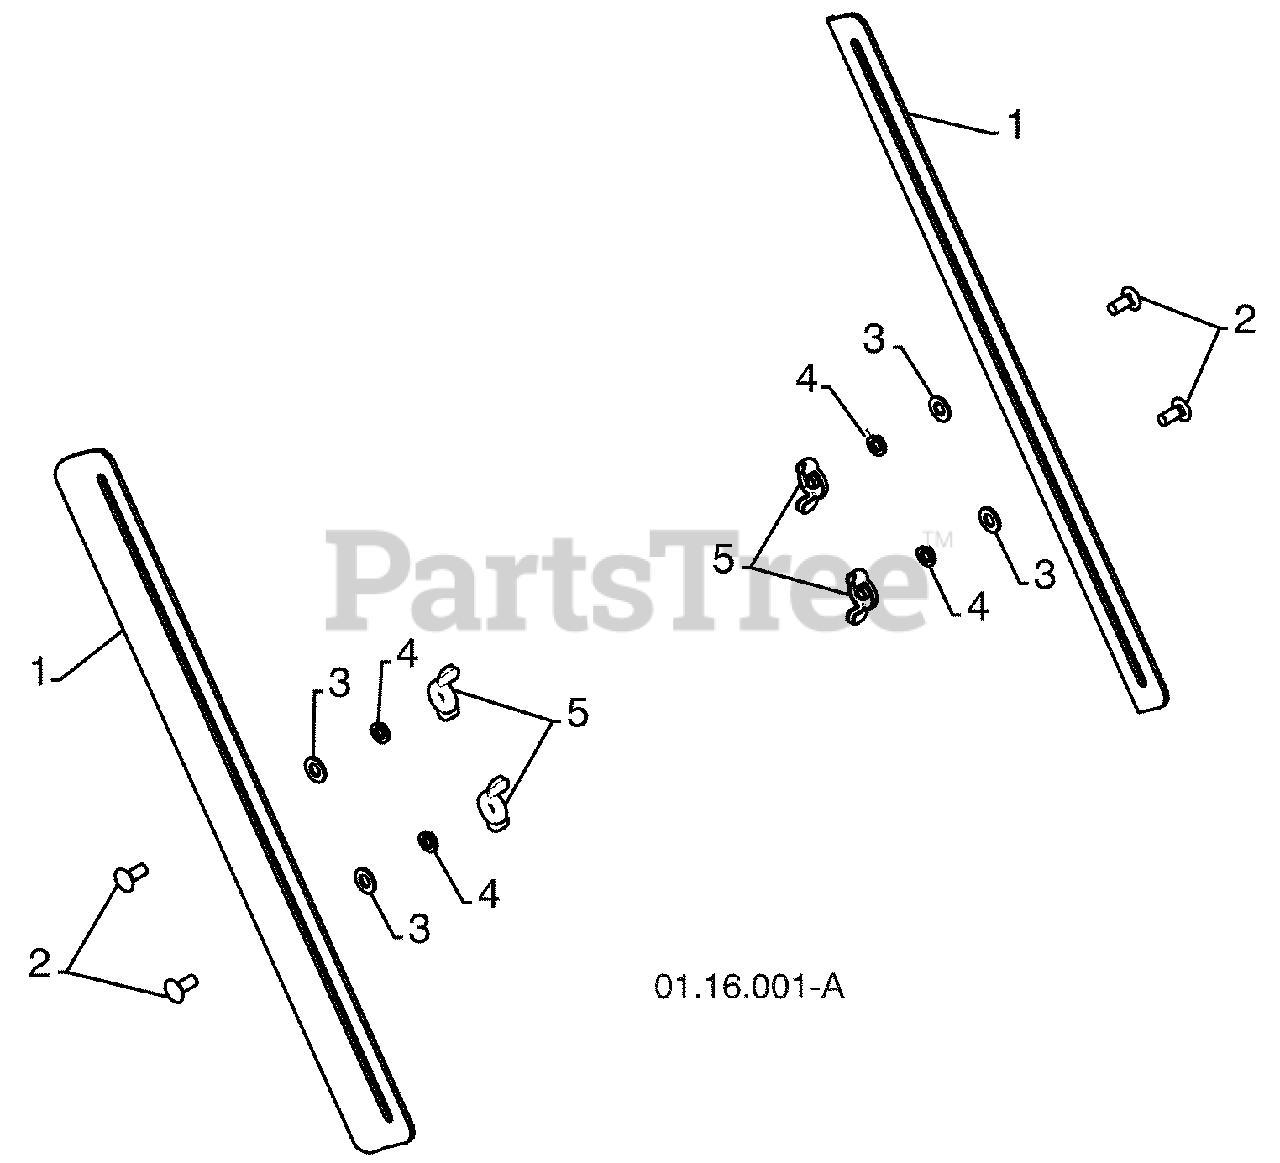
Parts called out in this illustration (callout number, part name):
1	DRIFT CUTTER BAR
2	CARRIAGE BOLT 5/16-18 X .750
3	PLASTIC WASHER
4	LOCKWASHER 5/16
5	NUT 5/16-18
